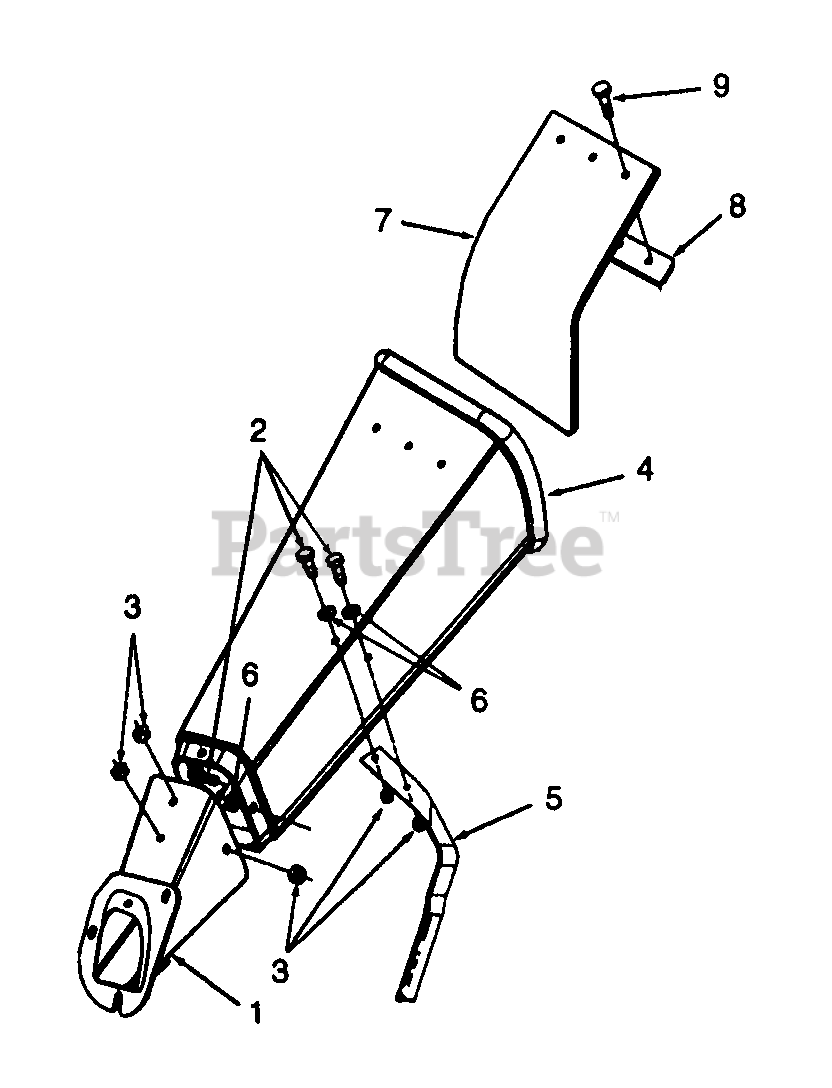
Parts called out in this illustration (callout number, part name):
1	Chute Assembly, Chipper
2	Screw, Hex Cap, 1/4-20 x .625
3	Nut, Hex Flange Lock, 1/4-20
4	Chute, Chipper
5	Bracket, Chipper Chute Support
6	Washer, Flat, .28 x .74 x .63
7	Flap, Chipper Chute
8	Strip, Chute Flap
9	Rivet, Pop, .156 x .504
